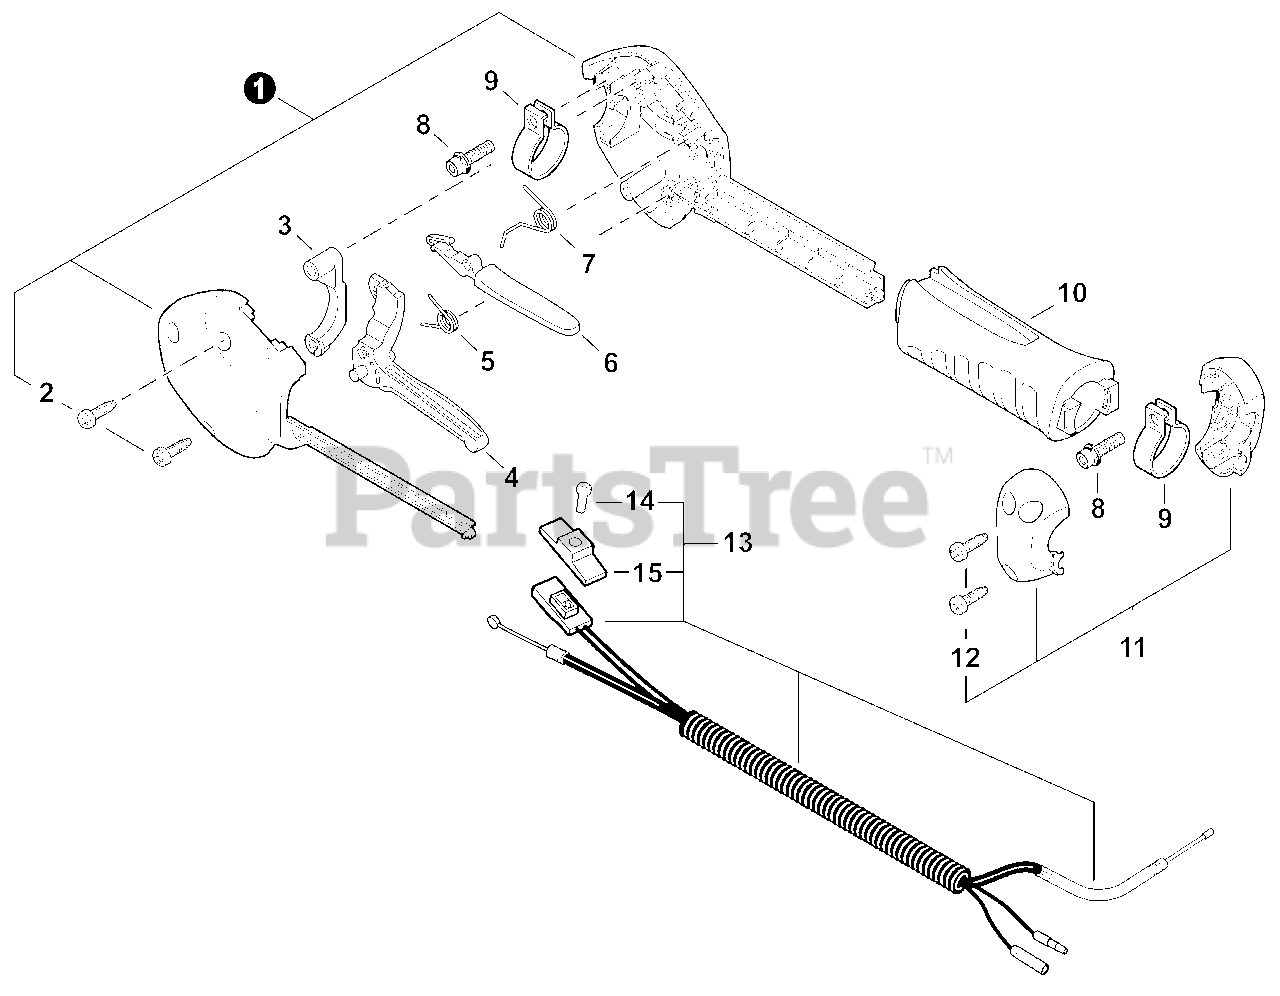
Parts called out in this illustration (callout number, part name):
1	HANDLE KIT, CONTROL
3	LOCKOUT, THROTTLE
4	TRIGGER, THROTTLE
5	SPRING, TORSION
6	LEVER, THROTTLE LOCKOUT
7	SPRING, TORSION
8	BOLT 5×20
10	GRIP, HANDLE
11	FIXTURE SET, HANDLE
13	CABLE ASSY, CONTROL
14	SCREW 3×10
15	KNOB, SWITCH - ORANGE
